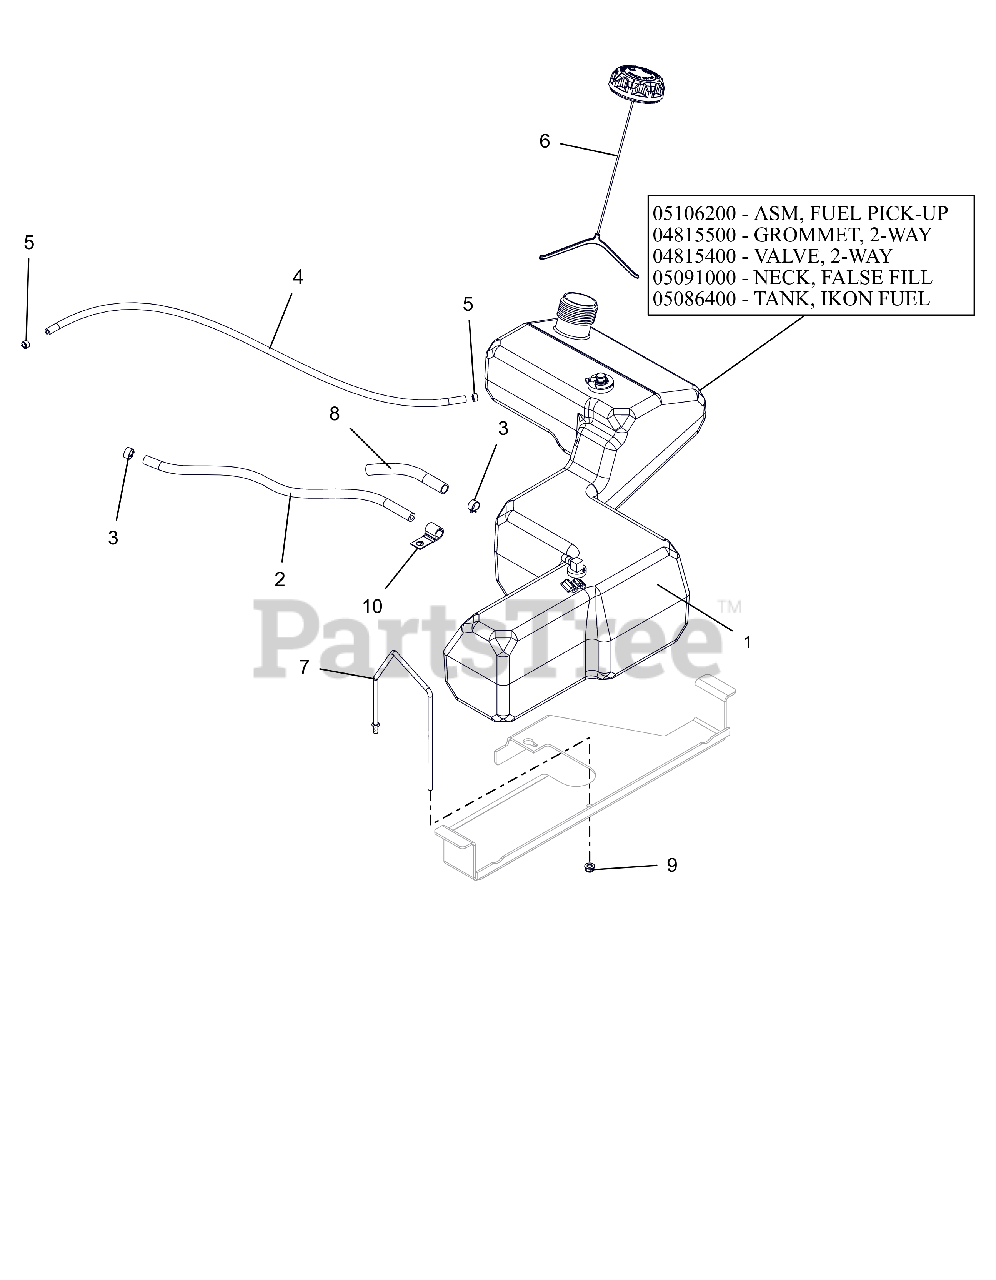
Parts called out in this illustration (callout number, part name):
1	ASSEMBLY, FUEL TANK IKON(2017)
1	ASM, IKON FUEL PICK-UP
1	GROMMET, 2-WAY
1	VALVE, 2-WAY
1	NECK, FALSE FILL-2017 IKON
1	TANK, IKON FUEL (2017)
2	HOSE, .25 LOW-PERM BULK GAS
3	CLAMP, FUEL LINE
4	HOSE, .188 LOW-PERM BULK GAS
5	CLAMP-HOSE, SPRING .188
6	CAP, FUEL VENT-IN 2.25" RATCH.
7	BRKT, FUEL TANK HOLD DOWN
8	WRAP, ANTIABRASION .5X.064WALL
9	@NUT-LK-NYL-FLG .25-20 YWZC
10	J-CLAMP
